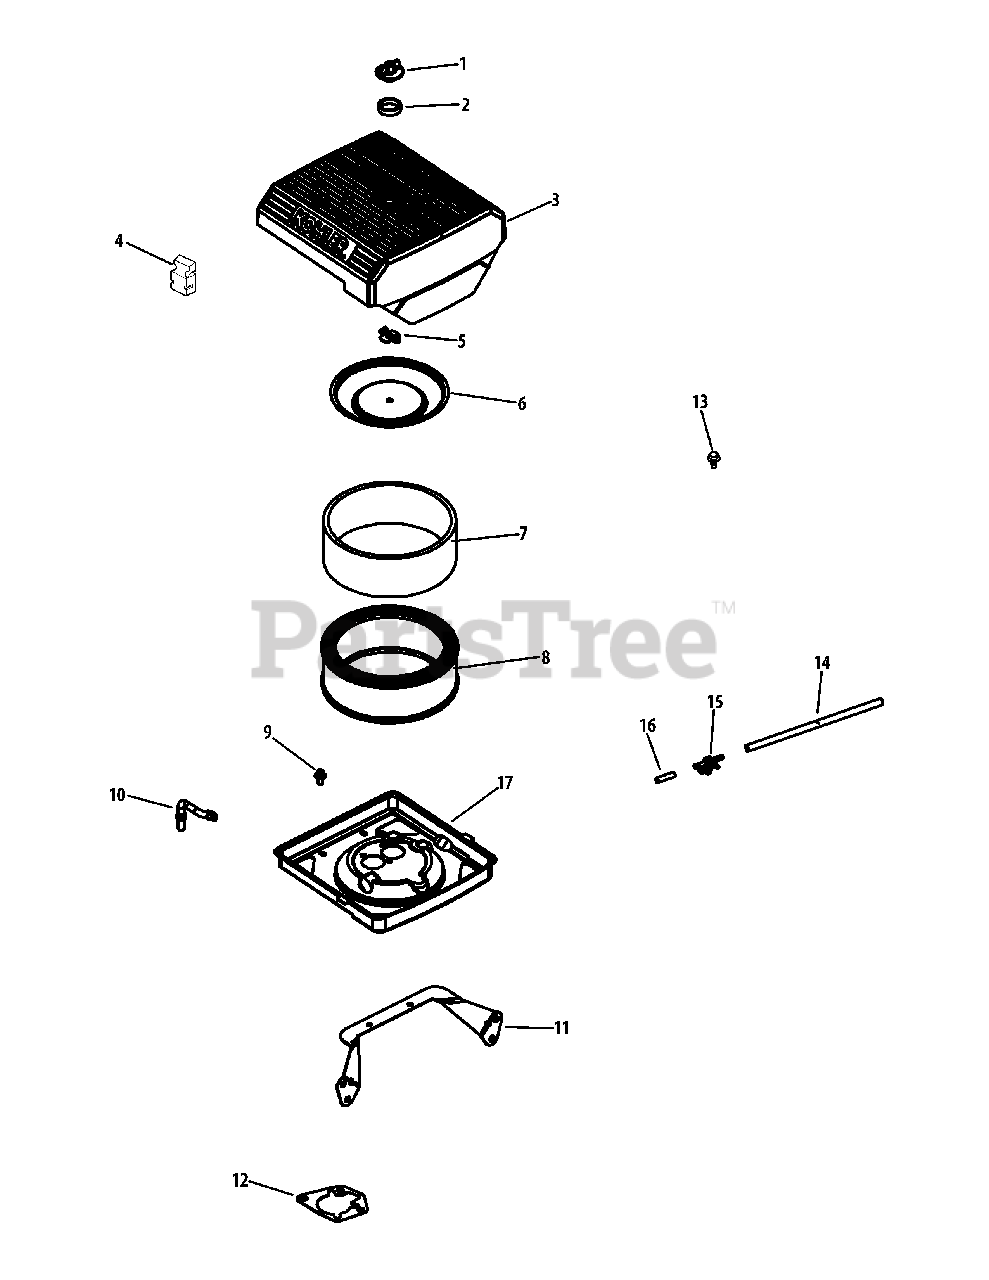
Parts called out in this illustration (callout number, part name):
4	Inner Air Cleaner Seal
6	Inner Air Cleaner Cover
7	Pre-cleaner Element (Low)
8	Air & Pre Cleaner Element
9	Evaporative Hose Connector
11	Air Cleaner Base Bracket
12	Air Cleaner Base Gasket
13	Thread Forming Screw
14	Evaporative Hose, 20"
15	Evaporative Connector
17	Air Cleaner Base Kit
NS	Knob Kit w/ Seal
NS	Evaporative Hose Connector
NS	Flange Thread Screw, M6 x 1.0 x 16
NS	Air Cleaner Bracket
NS	Intake Manifold Kit
NS	Carburetor Gasket
NS	Intake Port O-Ring
NS	Flange Screw, M6 x 1.0 x 40
